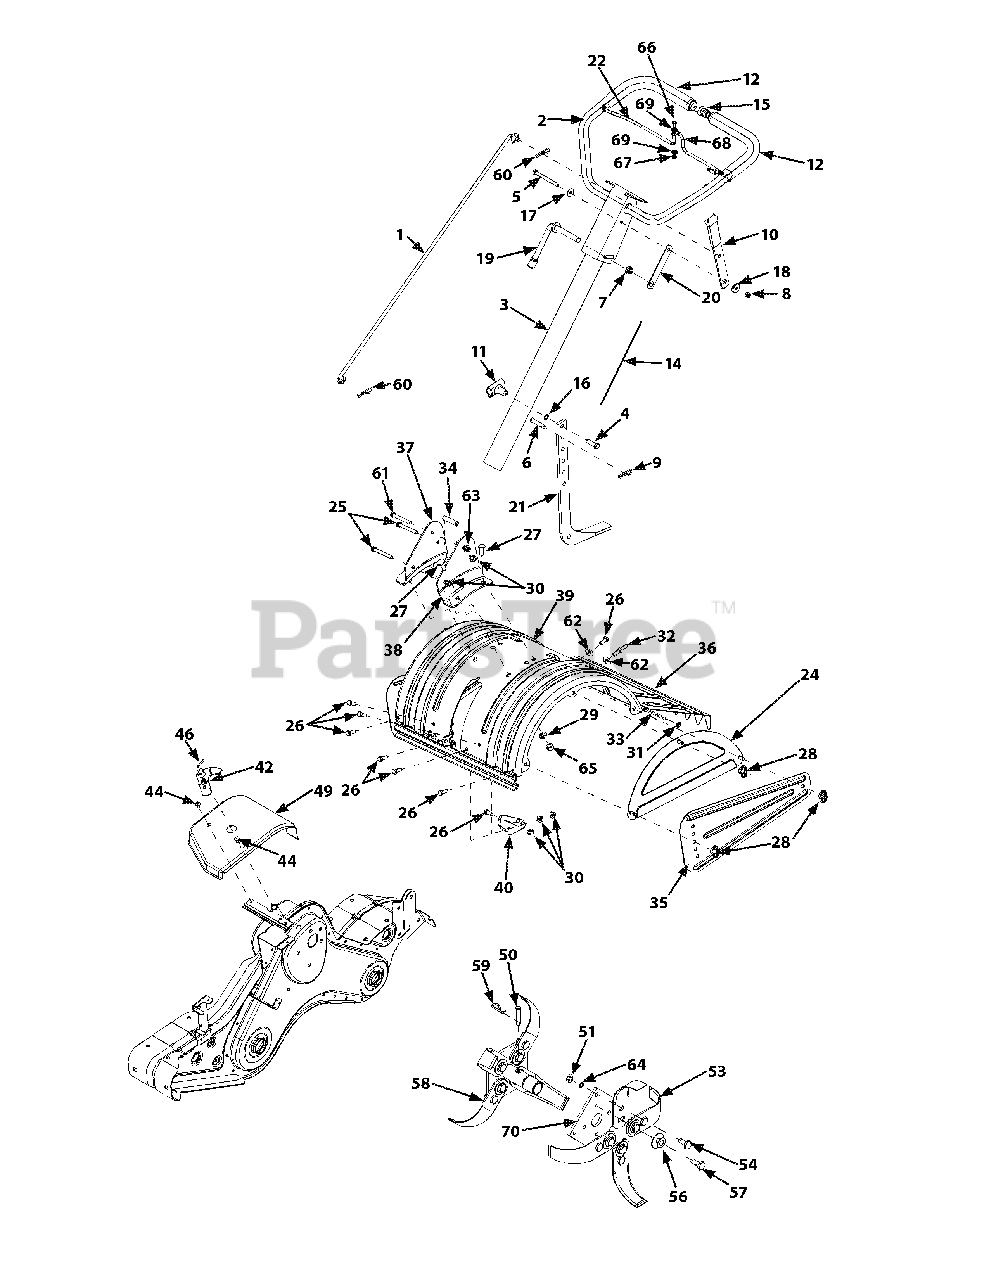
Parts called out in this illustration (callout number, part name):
1	Shift Rod
2	Upper Handle Assembly
3	Lower Handle Assembly
4	Hex Screw, 3/8-16 x 1.25
5	Hex Screw, 5/16-18x 3.25
6	Clevis Pin, 3/8-1.62
7	Flange Lock Nut, 3/8-24
8	Hex Lock Nut,5/16-18
9	Cotter Pin
14	Cable Tie
16	Flat Washer, 3/8 ID x .620 OD
17	Bell Washer, .340 ID x .872 OD
18	Shoulder Spacer
19	Handle Adjustment Crank
20	Hex Nut Retainer Bracket
23	Shift Lever Rod
24	Tine Shield Cover Assembly
25	Hex Cap Screw, 5/16-18 x 2.75
26	Hex Cap Screw, 5/16-18 x .750
27	Carriage Bolt, 3/8-16 x 1.0
29	Lock Washer, 3/8
30	Flange Nut, 5/16-18
31	Cap Nut
32	Hex Screw, 5/16-18 x .75"
34	Spacer, .322 x .625 x 2.0
36	Tine Shield Hinge Flap
37	RH Handle Bracket
38	LH Handle Bracket
40	Tine Shield Bracket
41	Shoulder Spacer Bracket
42	Shift Crank Assembly
44	Screw, 1/4-14 x .625
46	Spiral Pin, 3/16 x 1.0
50	Clevis Pin
51	Hex Nut, 3/8-24
53	13" Articulating Tine
54	Shoulder Bolt
55	Flat Washer, .51" ID x 1.50" OD
56	Bell Washer, .515" ID x 1.14" OD
57	Shoulder Bolt
58	Tine Adapter Assembly, 18"
59	Internal Cotter Pin
60	Cotter Pin
61	Hex Screw, 3/8-16 x 2.75"
62	Flat Washer
63	Flange Nut, 3/8-16
64	Lock Washer
65	Hex Nut, 3/8-16
66	Truss Screw, 1/4-20 x .65
67	Hex Lock Nut, 1/4-20
68	Battery Hose Clamp, 5/16
69	Flat Washer, .260 ID x .720 OD
70	Tine Adapter Plate
